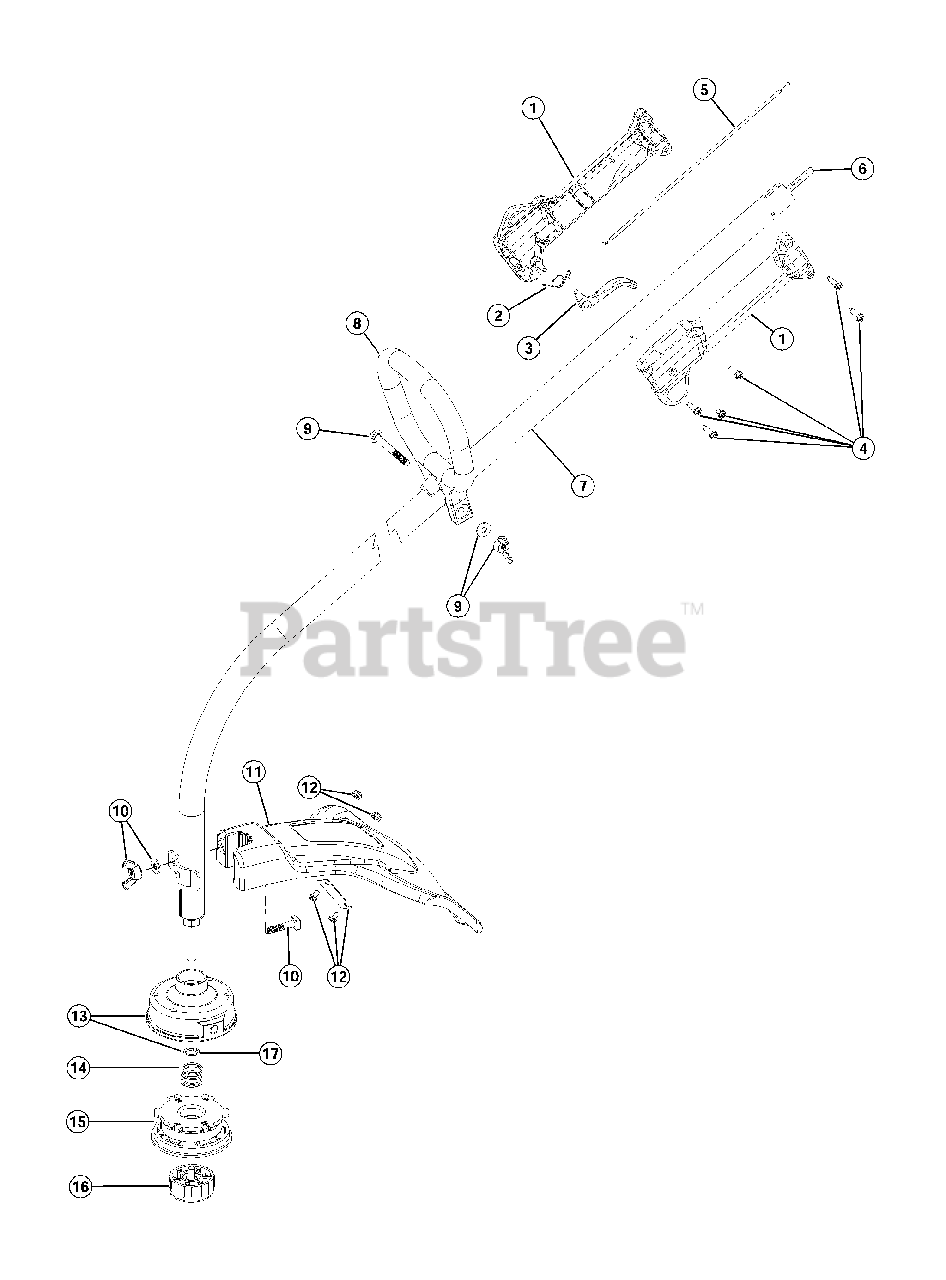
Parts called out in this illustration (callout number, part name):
1	Throttle Housing and Trigger Assembly
2	Throttle Trigger Spring
3	Throttle Trigger
4	Throttle Housing Screws
5	Throttle Cable
6	Flexible Drive Shaft
7	Drive Shaft Housing Assembly
8	D-Handle Assembly
9	D-Handle Hardware
10	Guard Mounting Hardware
12	Blade Assembly
13	Outer Reel w/Retainer
14	Spring
15	Inner Reel
16	Bump Knob
17	Retainer
